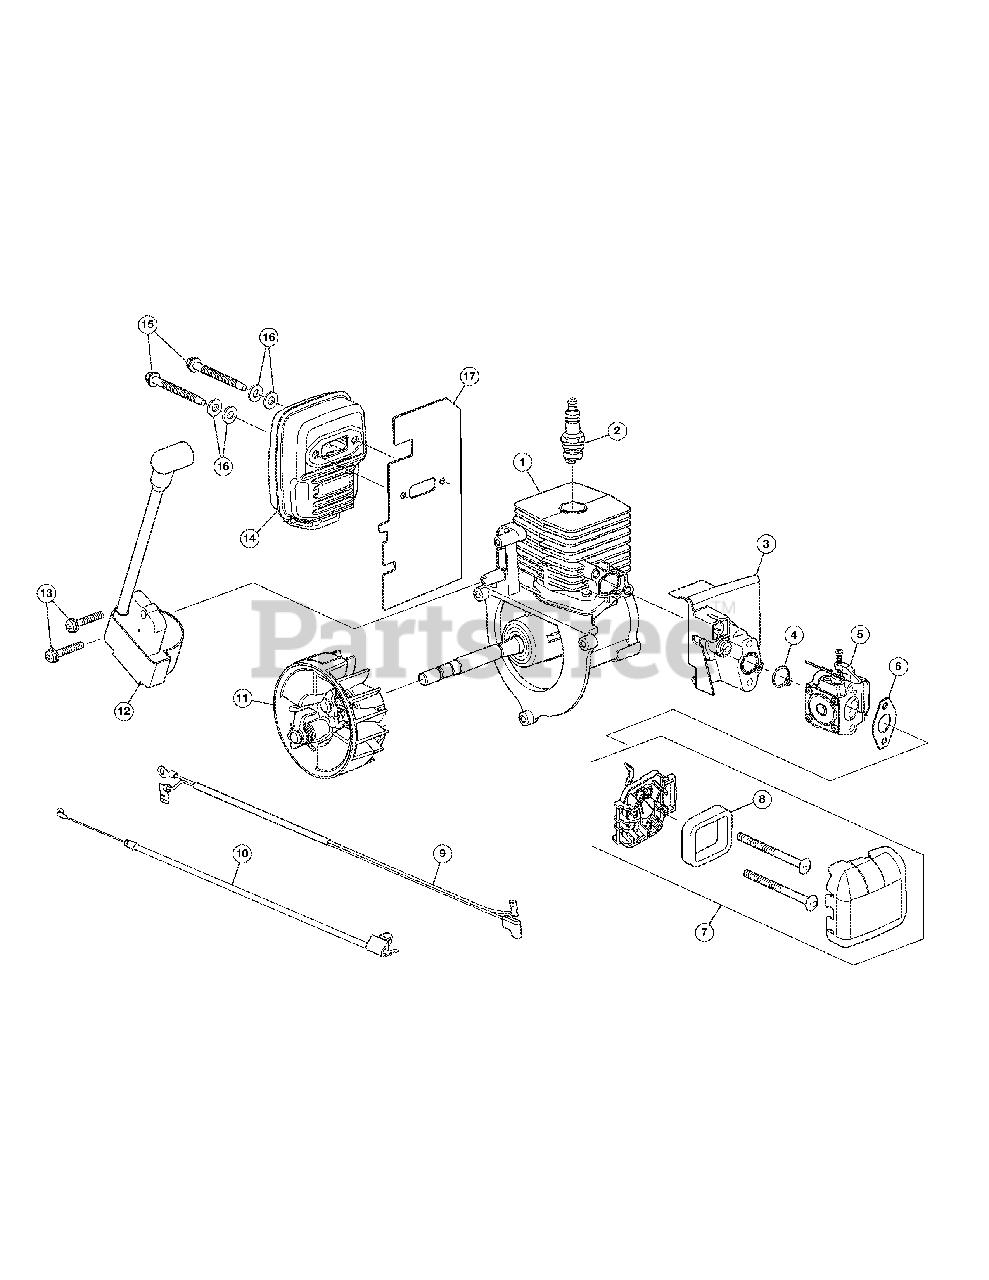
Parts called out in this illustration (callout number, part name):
1	Shortblock Assembly
2	Spark Plug
3	Insulator Assembly (Incl. 4)
4	O-Ring
5	Carburetor
6	Carburetor Gasket
7	Air Cleaner Assembly (Incl. 8)
8	Air Cleaner Filter
9	Lead Wire
10	Throttle Cable
11	Flywheel Assembly
12	Module Assembly (Incl.13)
14	Muffler Assembly (Incl. 15, 16 and 17)
15	Muffler Screws
16	Washers
17	Muffler Gasket
